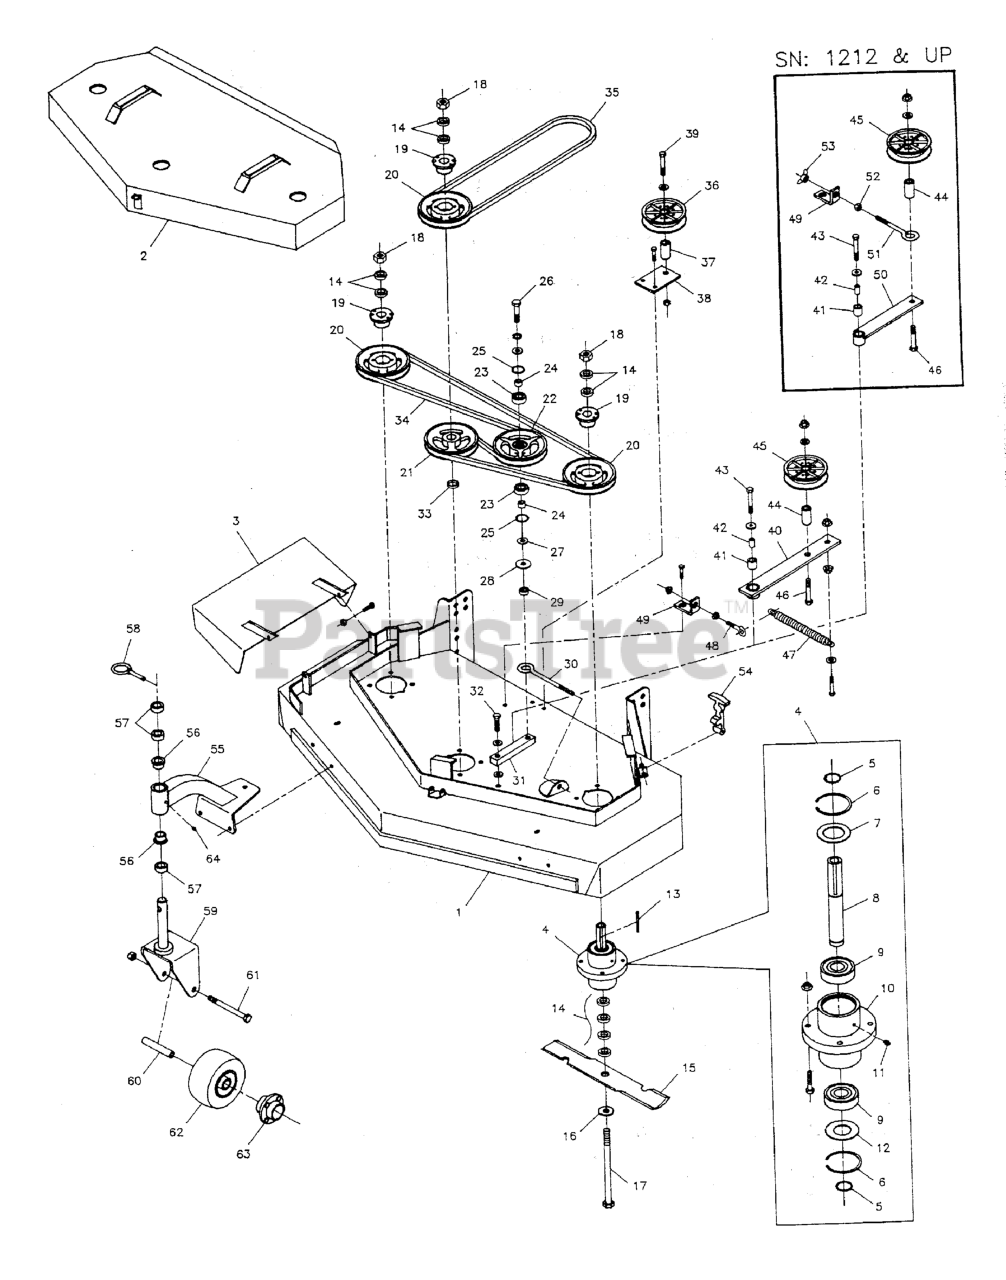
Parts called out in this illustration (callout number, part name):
1	48" MOWER HOUSING ASSEMBLY
2	48" DECK GUARD
3	CHUTE, DISCHARGE WELDMENT
4	SPINDLE ASSEMBLY, Complete
5	SNAP RING, External
6	SNAP RING, Internal
7	SPINDLE WASHER, Top
8	SPINDLE SHAFT
9	BEARING
10	SPINDLE HOUSING
11	GREASE FITTING
12	SPINDLE WASHER, Bottom
13	KEY, 1/4 SQ. X 2-1/2
14	SPACER, .63 x 1.06 x .23
15	MOWER BLADE, 16-1/4"
16	WASHER, 5/8" USS
17	BOLT, 5/8-11 x 9-1/2
18	NUT, 5/8-11 Hex
19	BUSHING, Tapered Hub
20	PULLEY, Spindle
21	SPINDLE PULLEY
22	IDLER PULLEY, Complete
22	PULLEY, Idler
23	BEARING, BALL 11/16X1-9/16X15/32
24	INSERT, Bearing
25	SNAP RING, Internal
26	BOLT, 1/2-20 X 2-1/4 GD5 CZ
26	BOLT, 1/2-20 X 1-3/4" GD8 CZ
27	WASHER, 1/2 SAE
28	WASHER, 1/2" USS
29	SPACER, .52 X 1.00 X .38
30	EYEBOLT, 3/8" x 8"
30	J-BOLT
31	ARM, Idler
31	IDLER ARM
32	BOLT, 7/16-20 X 1-3/4" GD.5
33	SPACER, 1.00 X 1.25 X .25
34	BELT, Blade Spindle
35	BELT, Deck Drive
36	PULLEY, Idler
37	SUPPORT, Idler
38	BRACKET, Idler Pulley
39	BOLT, 1/2-13 X 4" GD5 CZ
40	Idler Arm w/Bushing
41	BUSHING, Brass
42	SPACER, .32 x .75 x 1.06
43	BOLT, 5/16-18 x 1-3/4
44	SUPPORT, Idler
45	PULLEY, Idler
46	BOLT, 3/8-16 X 3" GD5 CZ
47	SPRING, Extension
48	EYEBOLT
49	SPRING ANCHOR
50	ARM, Idler
51	EYEBOLT, 3/8" X 6"
52	NUT, 3/8-16 Hex
53	NUT, 3/8-16 Wing Nylon Lock
54	RUBBER LATCH
55	CASTER MOUNT, Complete
56	BUSHING, FLANGE
57	SPACER, 1.02 x 1.56 x .50
58	PIN, Lynch
59	YOKE, Caster
60	AXLE, Caster Wheel
61	BOLT, 1/2-13 x 5-1/2
62	WHEEL & TIRE ASSEMBLY, White, 9 x 3.5 x 4, Complete
63	Hub Complete (Stamped M)
64	GREASE FITTING
